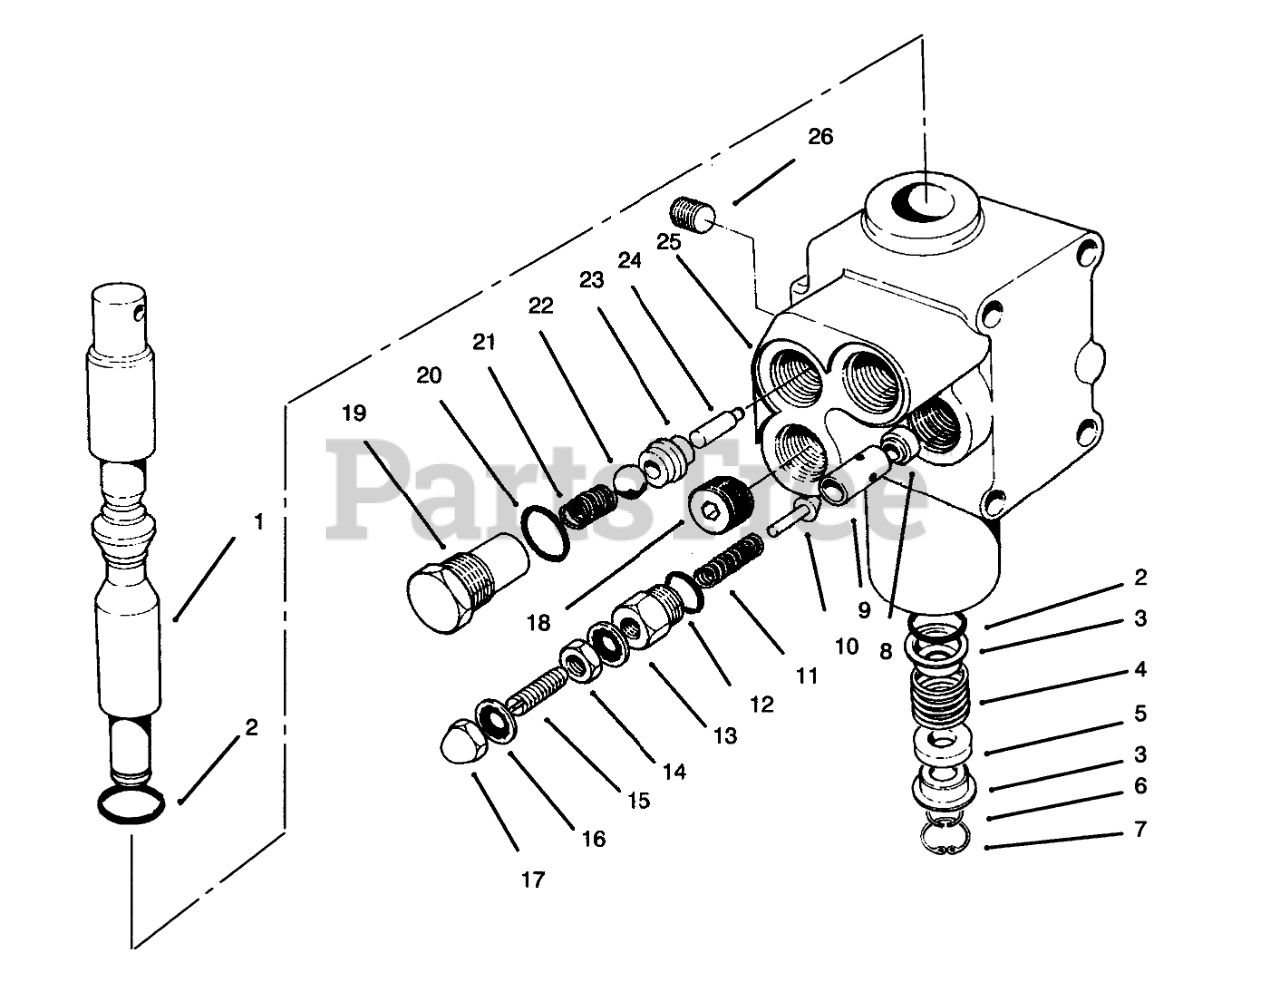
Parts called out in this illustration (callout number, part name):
1	SPOOL
2	O-RING
3	RETAINER
4	SPRING
5	FLOAT SPACER
6	RING-SNAP
7	RING-SNAP
8	SEAT-RELIEF
9	Guide
10	Plunger
12	"O"Ring
13	Cap-PV Adjustment
14	Nut
15	Screw-Set
16	Stat O Seal
17	Nut-Acorn
20	O-RING
21	SPRING
23	SEAT-VALVE
